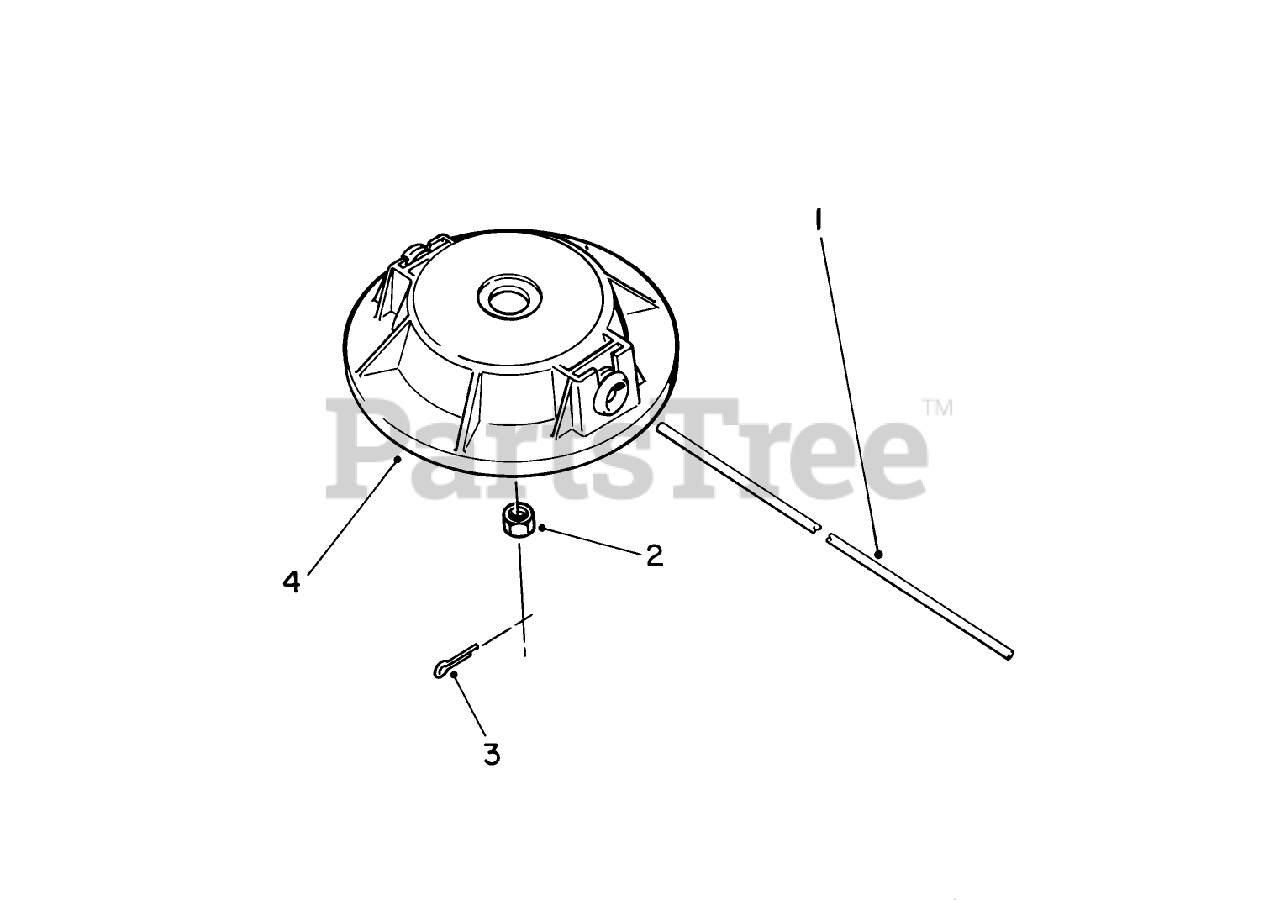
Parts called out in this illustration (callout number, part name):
1	Line-Cutting
3	1/16 X 1 LG COTTER PIN
4	CUTTER HEAD-PLASTIC
